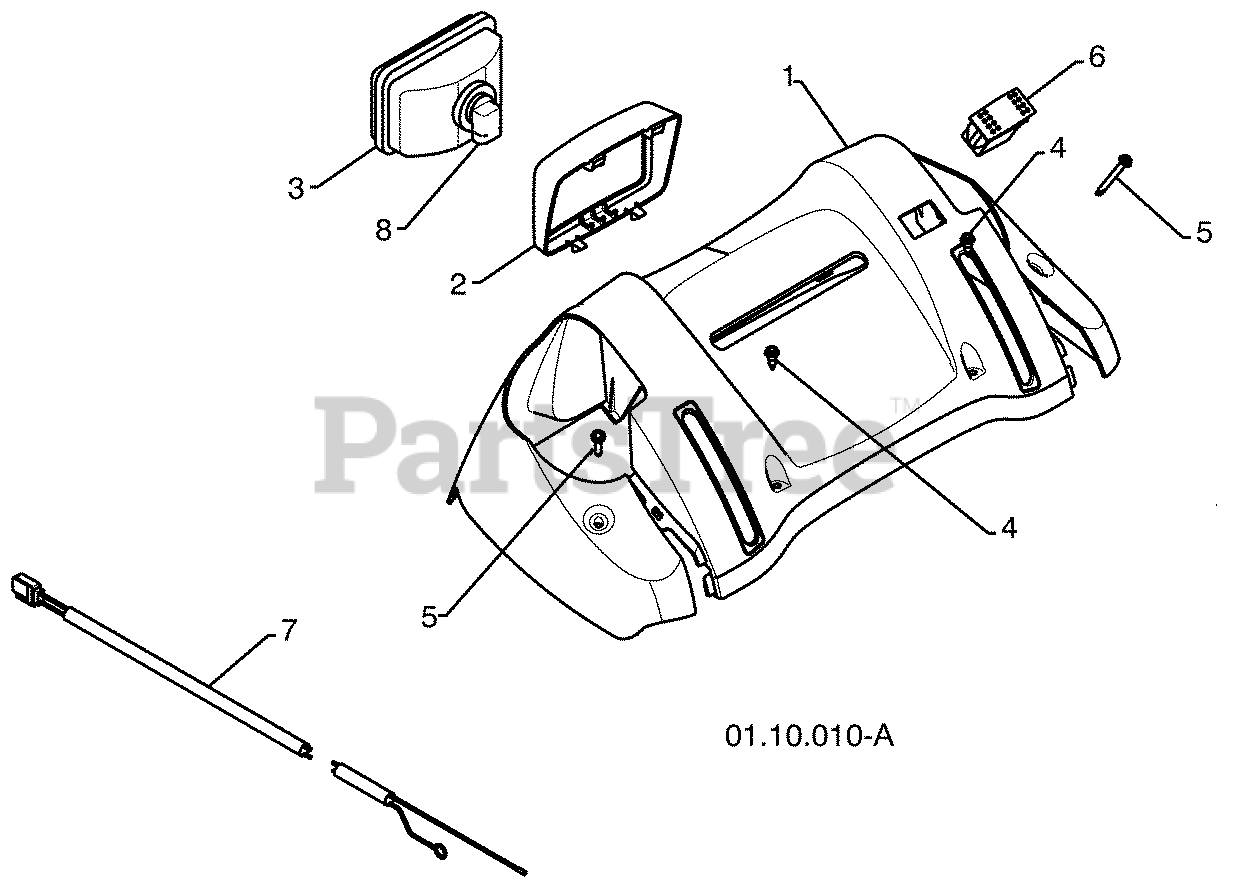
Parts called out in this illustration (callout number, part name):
1	CONSOLE PANEL GRAY
2	HEADLIGHT BEZEL GRAY
3	HALOGEN HEADLIGHT
4	SHOULDER SCREW 10-24 X .625
5	SCREW 10-24 X 1.25
6	GRIP SWITCH
7	WIRE HARNESS
